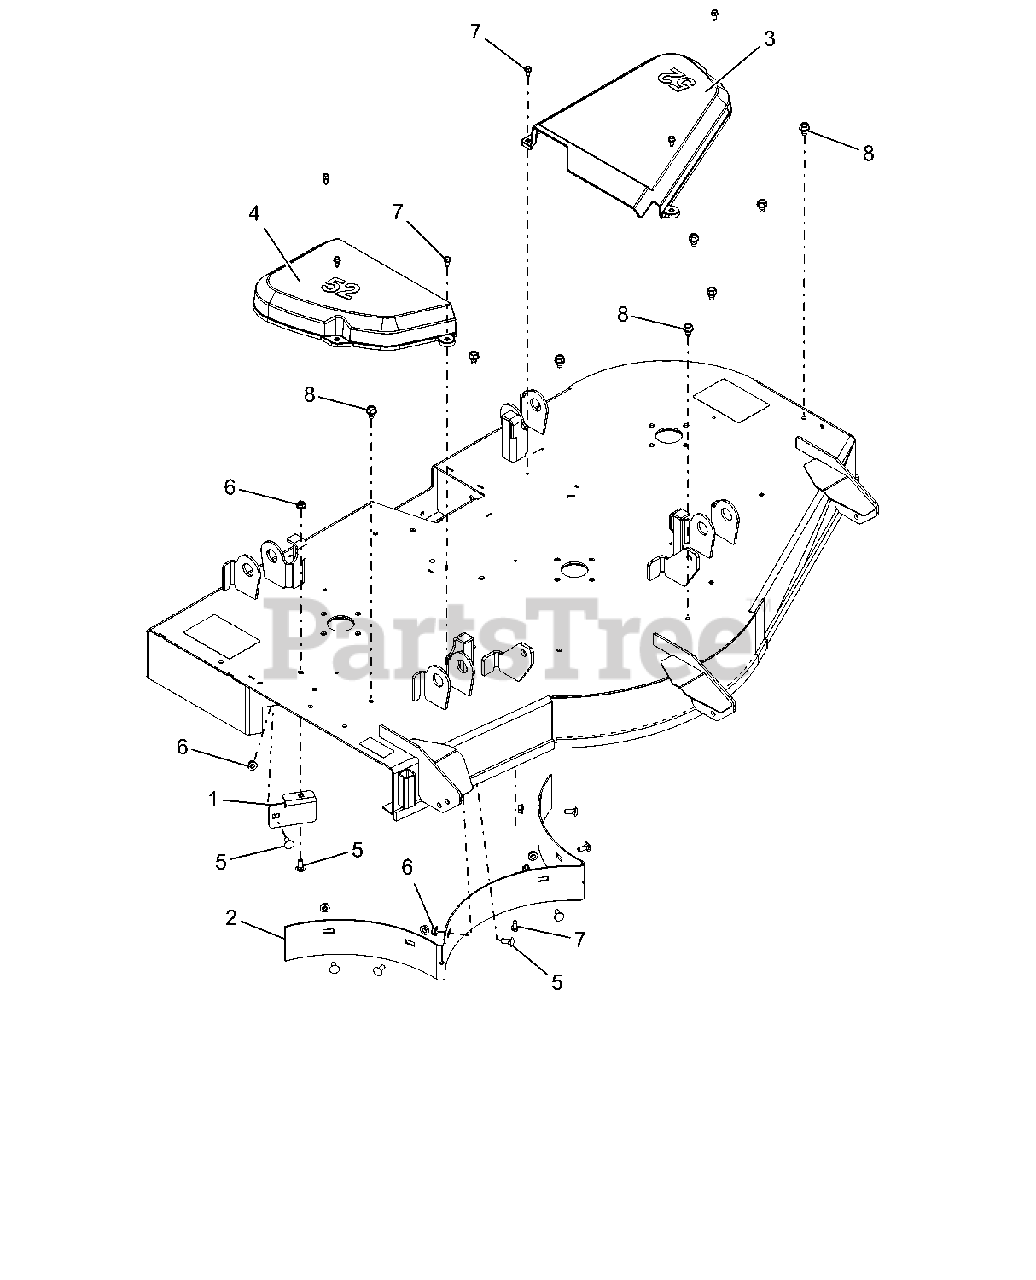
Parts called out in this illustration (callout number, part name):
1	STRIP, DEFLECTOR 52"
2	BAFFLE, REAR - REMOVABLE 52"
3	COVER, BELT 52" LH
4	COVER, BELT 52" RH
5	BLT-RDHDSQNK .31-18X.75 G5 YWZC
6	NUT, LK-TOP-FLG .312-18 YWZC
7	SCR-TAP .25-20X.50 HWH TR YWZ
8	SCR-TAP .38-16X.50 HWH TR YWZ
